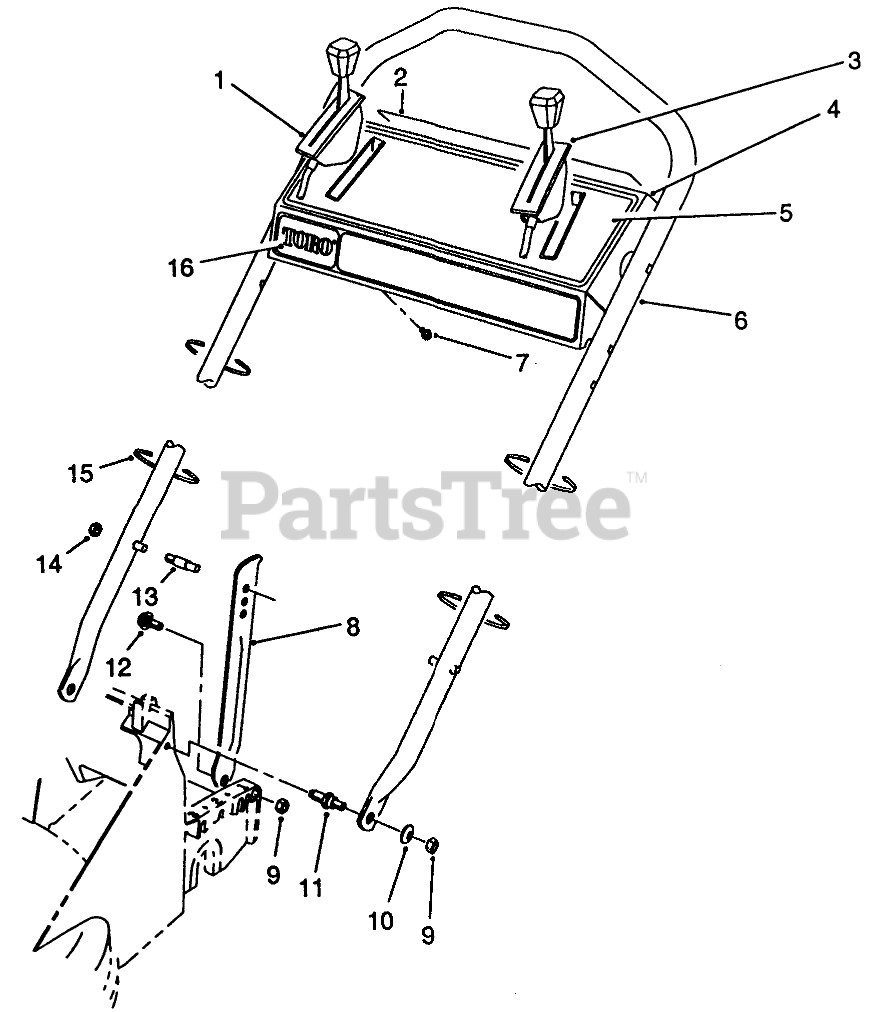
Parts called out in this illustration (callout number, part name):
1	Control-Ground Speed Bend Type #3 Sheath Lg. 51-1/4" Wire Lg. 2-1/8"
2	DECAL - PANEL, REAR
3	ControI-Throttle Bend Type #2 Sheath Lg. 44-3/4" Wire Lg. 2-1/2"
4	Panel-Control (Incl. Ref. #5 & 16)
5	DECAL - INSTRUCTION
6	HANDLE
7	SCREW-HWHTF
8	HANDLE LATCH
9	NUT-LOCK, NI
10	WASHER-PLAIN
11	SCREW - SHOULDER STUD
12	SCREW - SHOULDER
13	HANDLE PIN
14	NUT-LOCK, NI
15	TIE-CABLE
16	DECAL - TORO PANEL
